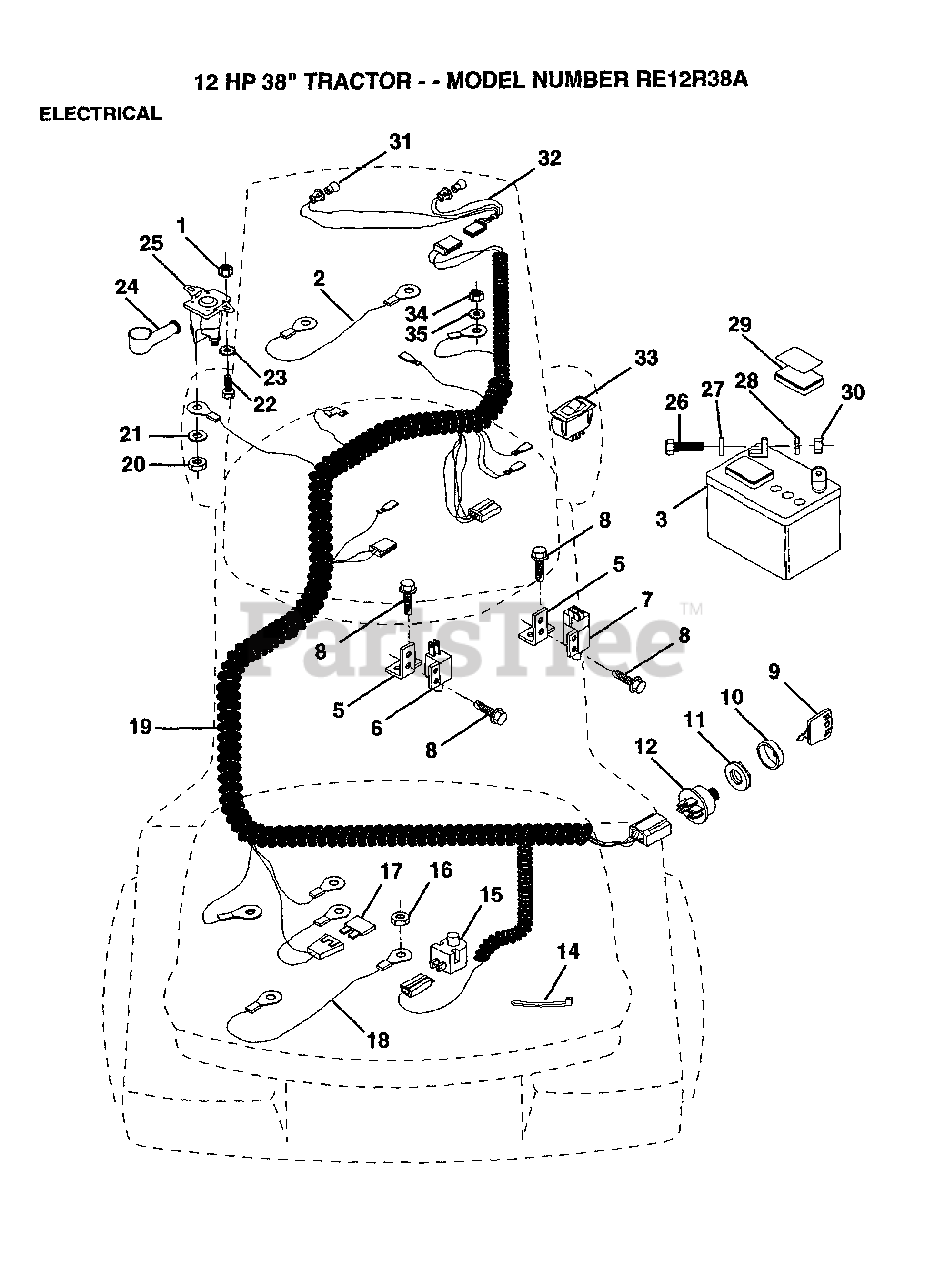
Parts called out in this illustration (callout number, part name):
1	NUT
2	CABLE ASM.
5	BRACKET LT
6	SWITCH-INTER. GT
7	SWITCH INTERLOCKT (2 2)
8	SCREW
9	KEY
11	NUT IGNITION (2 2) (3 2)
14	WIRE TIE
15	SWITCH SEAT *SUBS/2*
17	FUSE HYT
18	CABLE ASSY
20	NUT
22	BOLT
26	BOLT LT
27	WASHER
28	LOCKWASHER
33	SWITCH LT
34	NUT
35	LOCKWASHER
